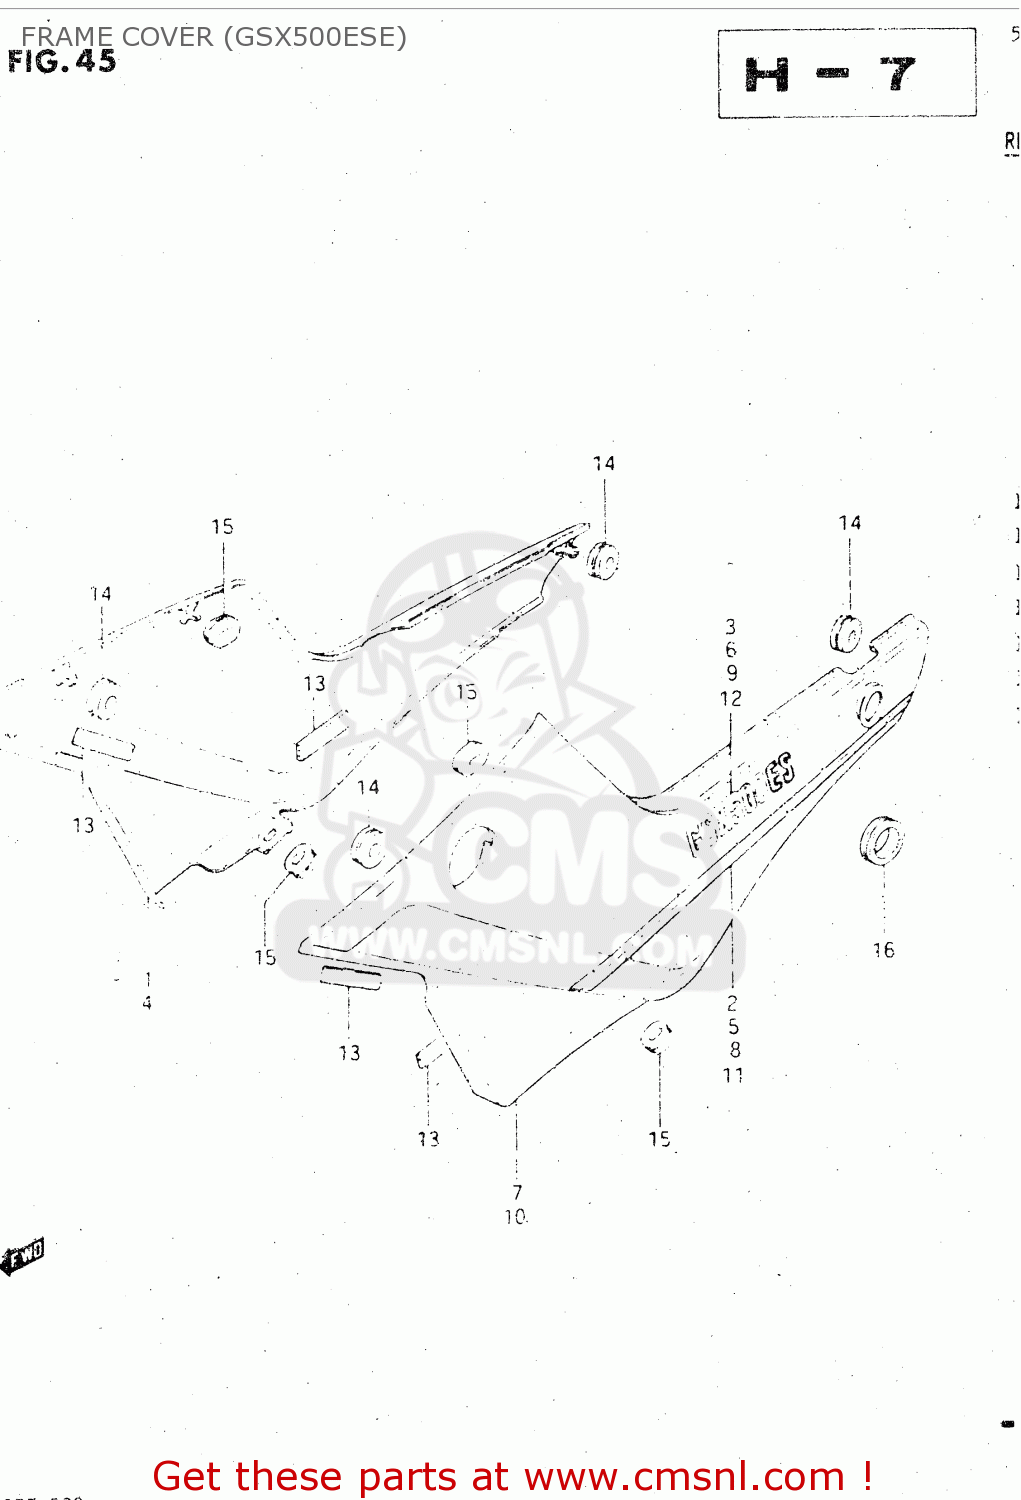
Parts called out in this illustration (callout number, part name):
1	COVER, FRAME RH
2	TAPE SET,FRAME COVER,RIGHT
3	EMBLEM
4	COVER, FRAME RH
5	TAPE SET, FRAME COVER RH
6	EMBLEM
7	COVER, FRAME LH
8	TAPE SET,FRAME COVER
9	EMBLEM
10	COVER, FRAME LH
11	TAPE SET, FRAME COVER LH
12	EMBLEM
13	RUBBER,FRAME COVER
14	CUSHION
15	CUSHION
16	GROMMET,SEAT LOCK HOLE
